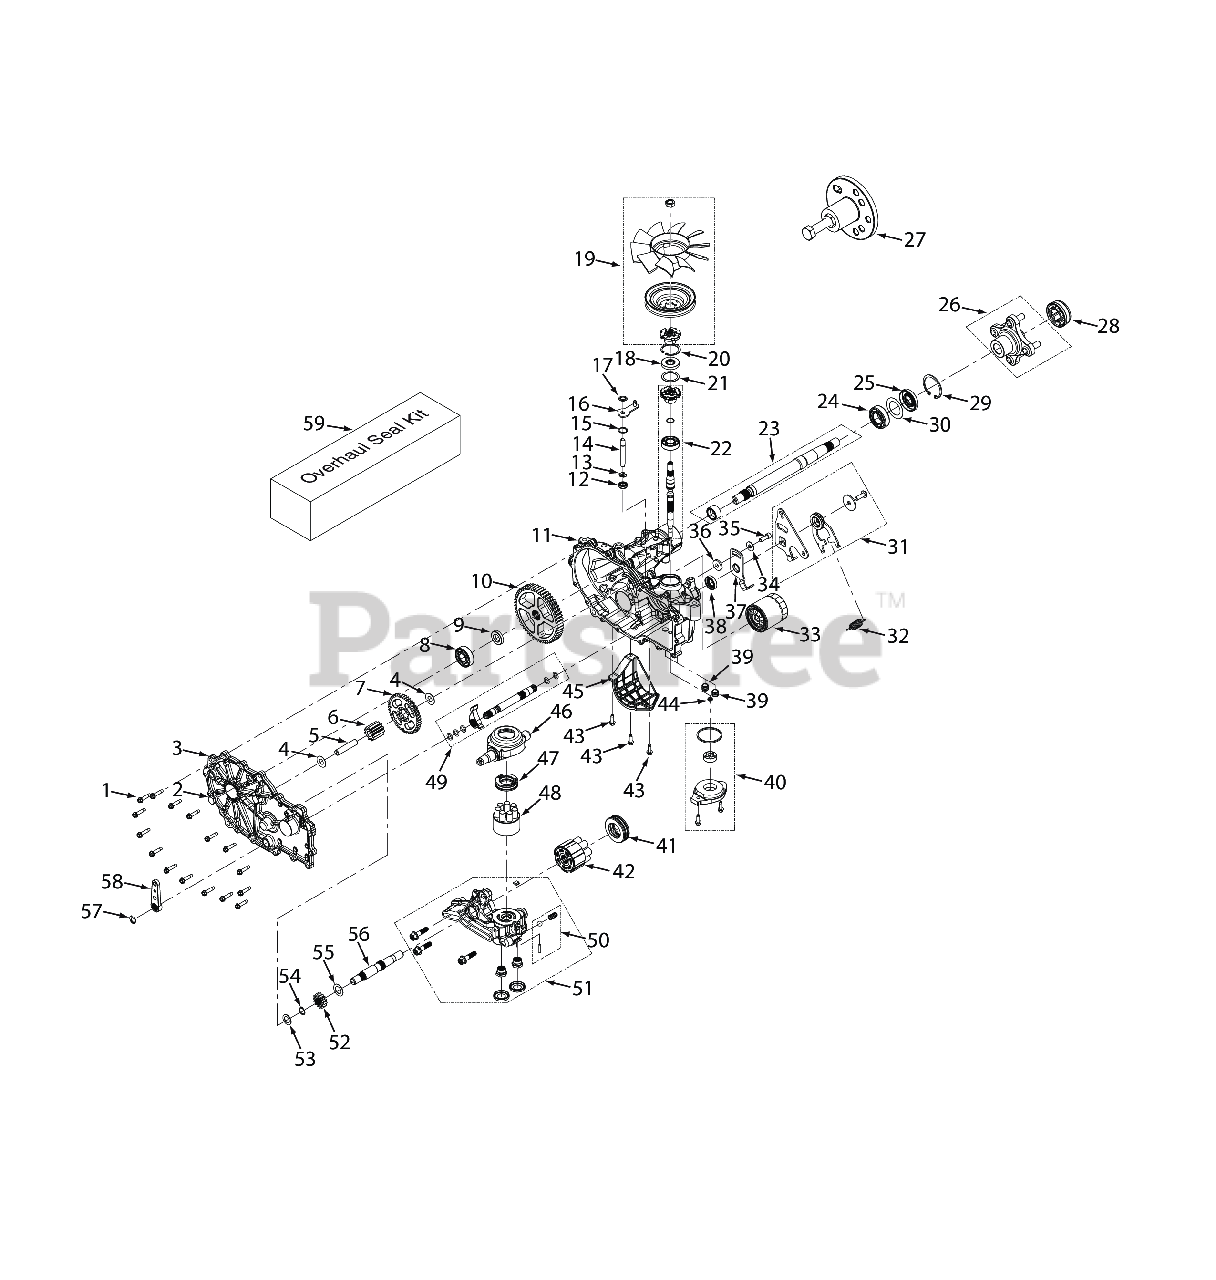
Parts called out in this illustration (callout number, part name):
1	Bolt, Hex Head 1/4-20 x 1-1/8"
2	Plug, External Hex Vent 9/16-18
3	Kit, Side Cover LH
3	Kit, Side Cover RH
4	Washer, .5 x 1.0 x .03
5	Jackshaft Pin
6	Gear, 11T
7	Gear, 45T
8	Kit, Bearing
9	Spacer, .750 x 1.320 x .257
10	Gear, 54T
11	Kit, Housing LH
11	Kit, Housing RH
12	Seal, Lip, .375 x .75 x .25
13	Ring, .Retaining .375 External
14	Rod, By-Pass
15	R i n g , Retaining .750 Internal
16	Arm, Bypass (LH)
16	Arm, Bypass (RH)
17	Ring, Retainging .375 External
18	Seal, Lip 17 x 40 x 7
19	Kit, Fan/Pulley
20	R i n g , Retaining 2.06 Internal
21	Washer, 1.23 x 1.56 x .04
22	Kit, Input Shaft
23	Kit, Shaft, Axle
24	Bearing, Ball 1.0 x 52 x 15 Open
25	Seal, Lip TC4 1.0 x 2.06 x .38
26	Hub, 4-Bolt
27	Kit, Hub Puller
28	Cap, Axle
29	R i n g , Retaining 2.06 Internal
30	Spacer, 1.355 x 2.035 x .021
31	Kit, RTN Bi-Directional (Right Side)
31	Kit, RTN Bi-Directional (Left Side)
32	Spring, Extension, RTN - 44lbs
33	Filter, Oil
34	Washer, 7/16 x 7/8 OD x .06 HT
35	Bolt, Hex Head Cap Screw 5/16-24 x 1" Patch
36	Spacer, .32 ID x 1.005 OD x .1495 Thk
37	Arm, Neutral (Left Side)
37	Arm, Neutral (Right Side)
38	Seal, Lip 18 x 32 x 7
39	Tube, Charge Triple O-ring
40	Kit, Charge Pump
41	Thrust Ball Bearing Assembly
42	Kit, 16cc Cylinder Block Assembly (steam
43	Bolt, 1/4-20 x 3/4"
44	Kit, Gerotor Seal
45	Filter Guard
46	Trunnion, Swashplate
47	Ball Thrust Bearing
48	Kit, Cylinder Block
49	Kit, Inboard, RH Rot B / LH Rot A (LH)
49	Kit, Inboard, RH Rot A / LH Rot B (RH)
50	Kit, Charge Relief
51	Kit, Charge Relief
51	Kit, Center Section, LH Charge
52	Washer, Flat, .71 x 1.16 x .04
53	Washer, HT .62 ID x 1.0 OD x .05 Thick
54	Ring, Retaining .625
55	Washer, .72 x 1.16 x .04
56	Shaft, Motor
57	Ring, Retaining External .375"
58	Handle, Brake
59	Kit, Outboard, RH Rot A / LH Rot B (RH)
